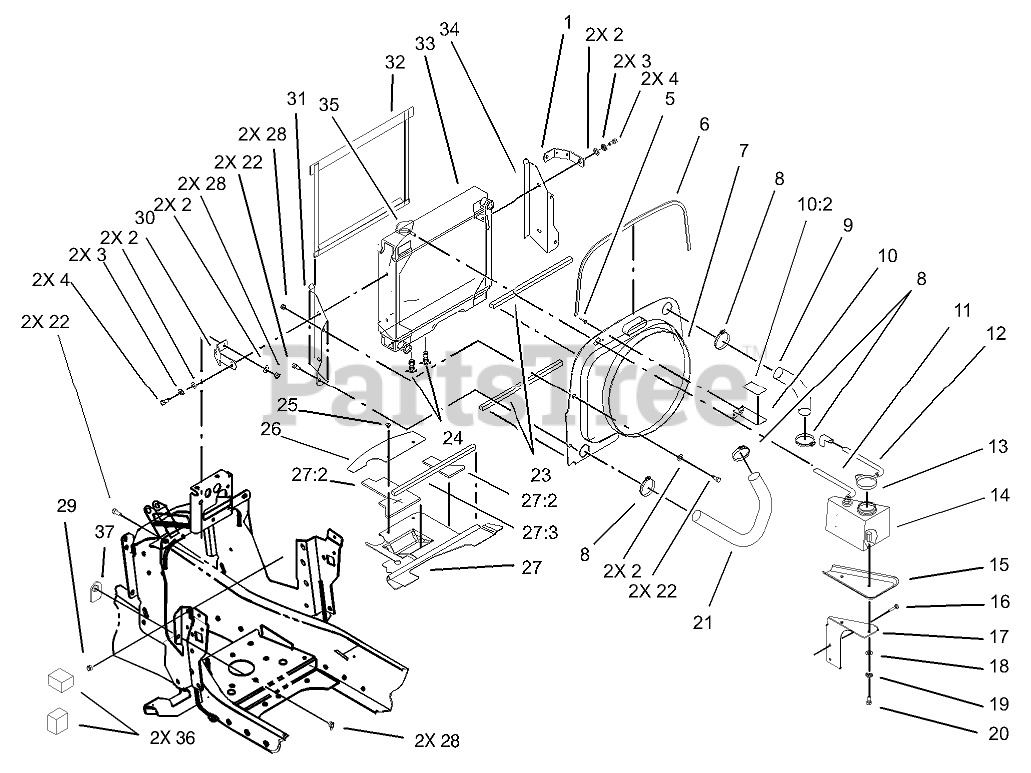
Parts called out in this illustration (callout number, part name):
1	Strap-Radiator
2	WASHER-PLAIN
3	WASHER-LOCK
4	SCREW-HH
5	RIVET-POP
6	TRIM - LOC 31"
6	Trim-Loc
7	SHROUD - FAN
8	CLAMP-HOSE
9	HOSE - RAD. DAIHATSU
10	FAN/DECAL ASM
10:2	DECAL - WARNING
11	HOSE - FUEL LINE
12	HOSE - OVERFLOW
13	CAP - COOLANT RESERVOIR
14	BOTTLE - OVERFLOW
15	TRAY - OVERFLOW
16	BOLT-CARR
17	Brkt-Bottle
18	WASHER-FLAT
19	WASHER-LOCK
20	SCREW-HH
21	HOSE - RAD. DAIHATSU
22	SCREW-HH
23	FOAM - RADIATOR/SHROUD
24	VALVE - DRAIN
25	RIVET - PLASTIC
26	BAFFLE - TOWER REAR
27	BAFFLE-TOWER ASM
27:2	FOAM - BAFFLE
27:3	FOAM - RADIATOR/SHROUD
28	NUT-LOCK, NI
29	NUT-HEX
30	Bracket-Relay
31	Support-Radiator RH
32	SCREEN - CHAFF
33	RADIATOR - DIESEL
34	Support-LH Radiator
35	CAP-RADIATOR
36	SEAL-FOAM, SIDE
37	WASHER - SPACER
